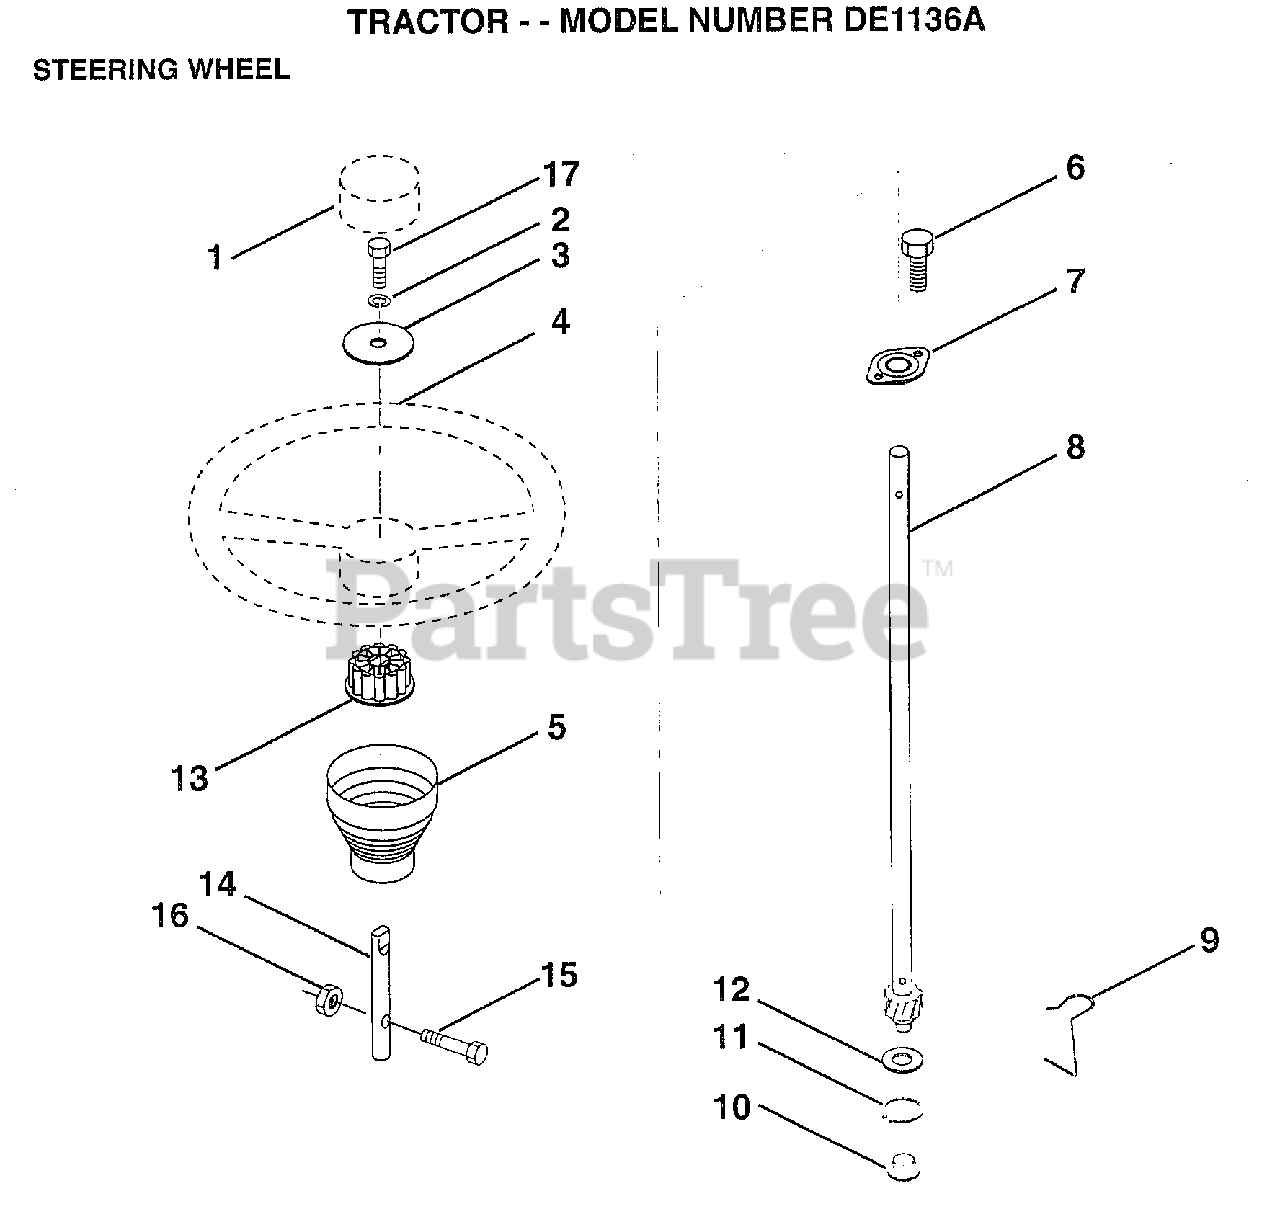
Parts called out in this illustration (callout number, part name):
1	CAP WHEEL STEER
2	LOCKWASHER
3	WASHER T
5	SLEEVE STEERING
6	"SCREW-TT,10-32 FL"
7	BUSHING.STR.623
8	SHAFT.STEERING.LR
9	STEERING CLIP
10	BUSHING STEER LWR
11	RING
12	WASHER LT
13	ADAPTER LT
14	EXT SHAFT STEERIN
15	BOLT
16	NUT
17	BOLT
